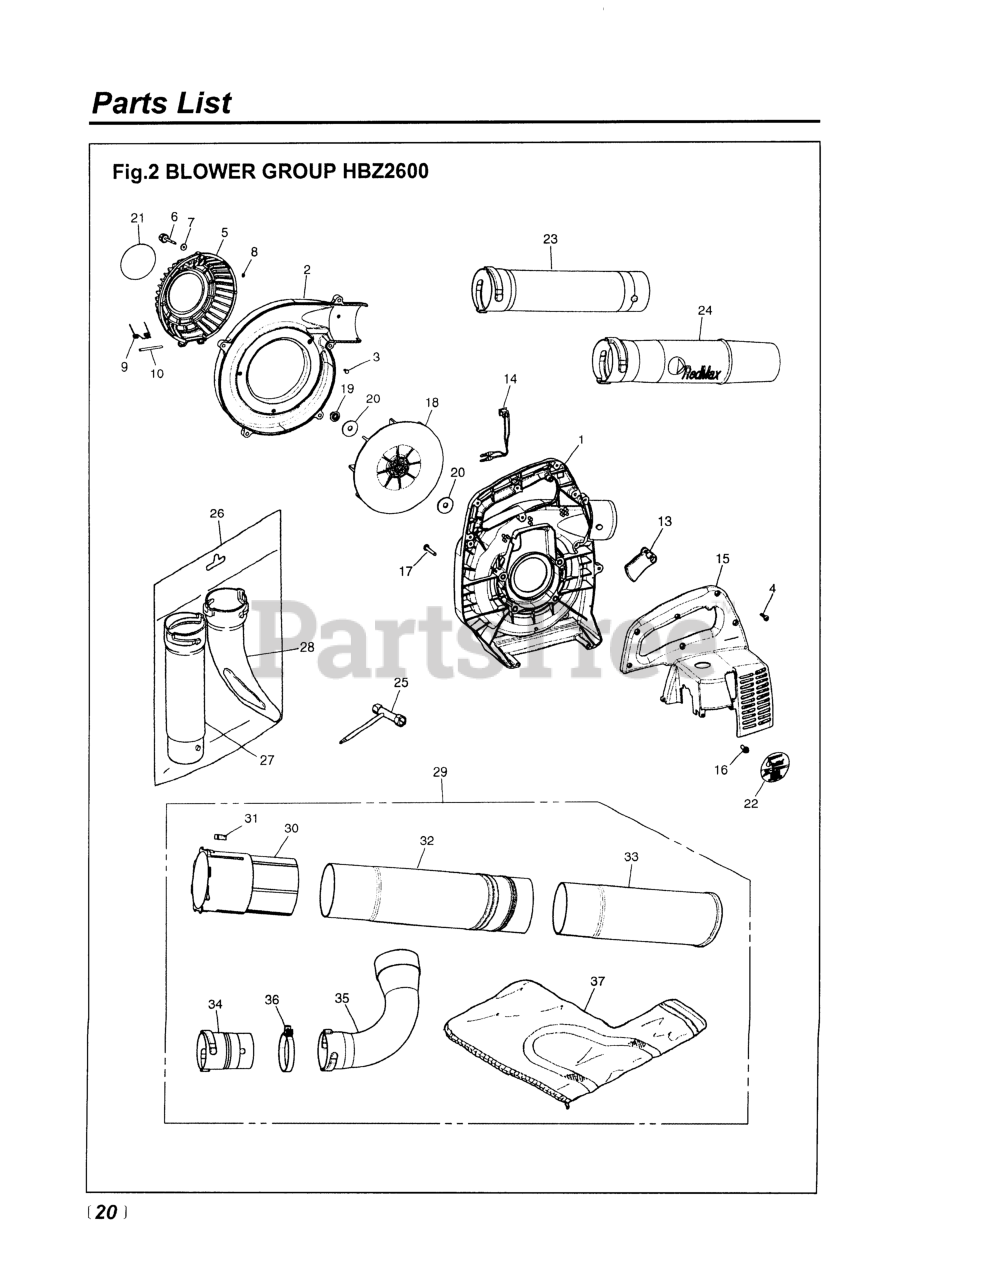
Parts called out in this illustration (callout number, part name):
1	848-L0F-55A1
2	VOLUTE COVER (HBZ 2500)
3	SCREW
5	GUARD NET
6	SCREW
7	WASHER
9	SPRING
10	SHAFT
13	LEVER
14	SWITCH
15	ENGINE COVER
16	BOLT
17	SCREW
18	FAN
20	WASHER
21	LABEL, CAUTION
22	LABEL, RECOIL
24	PIPE, END
26	FLAT NOZZLE SET
28	NOZZLE, FLAT
29	VACUUM KIT
30	PIPE, A
32	PIPE, B
33	PIPE, C
34	EXTENSION (PIPE)
35	ELBOW
36	CLAMP
37	BAG, DUST
